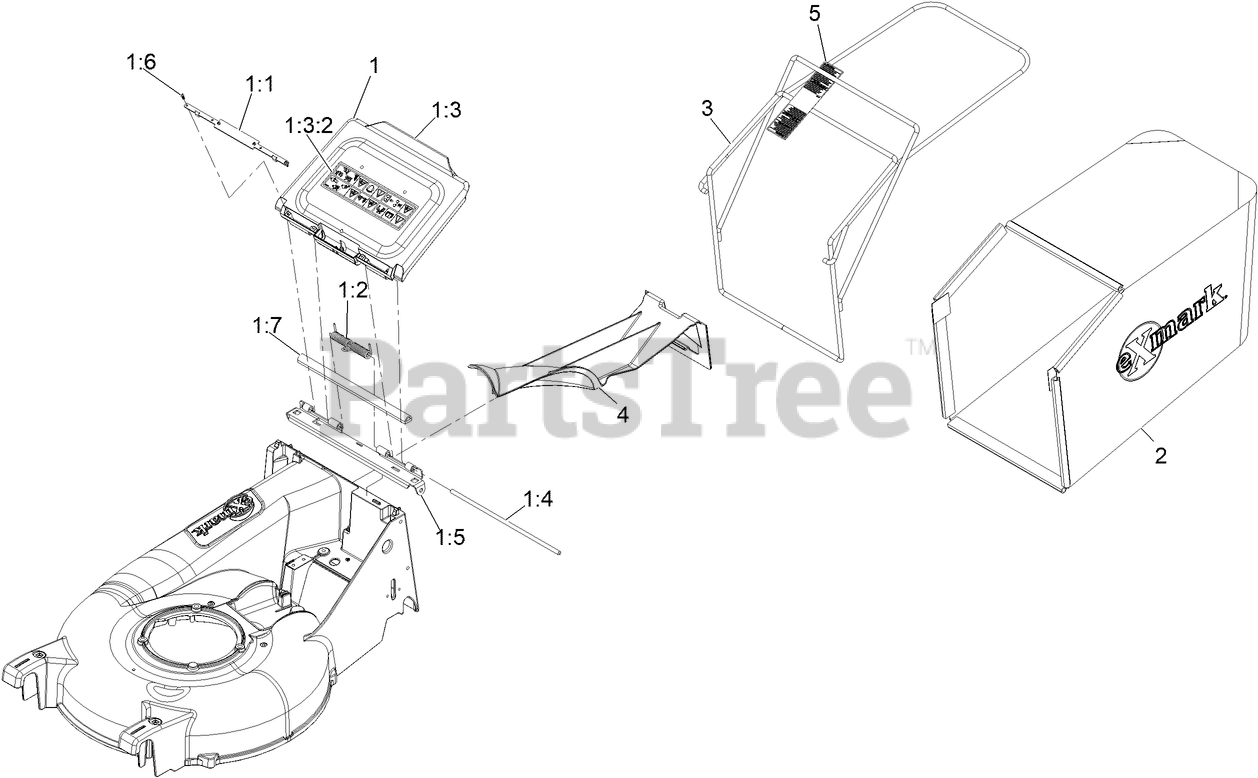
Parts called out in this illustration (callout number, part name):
1	DOOR ASM
1:1	X-REF 126-2628-03
1:2	SPRING-PLASTIC DOOR
1:3	ASM-DOOR & DECAL
1:3:2	DECAL-WARNING
1:4	PIN-DOOR PIVOT
1:5	X-REF TO 126-2636-03
1:6	SCR,TAP,6-19X7/16,PHPH, S
1:7	SEAL-EPDM FOAM BULB
2	BAG-GRASS EC21
3	WLD-BAG FRAME
4	PLUG,MULCH
5	DECAL-WARNING (BAG)
